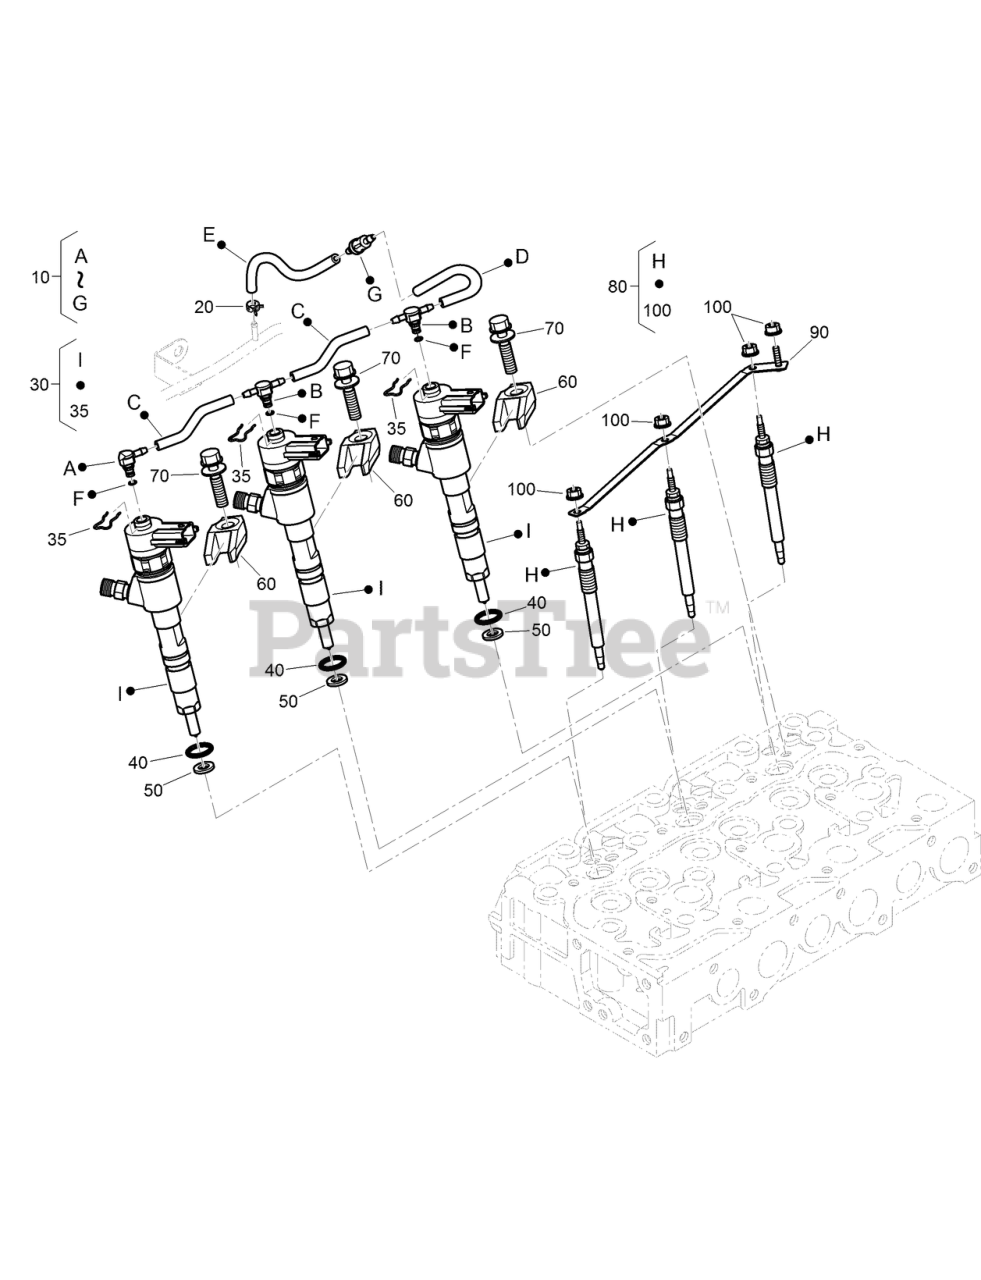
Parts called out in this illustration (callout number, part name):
10	OVER FLOW TUBE ASM
20	CLAMP-HOSE
30	INJECTOR ASM
40	O-RING
50	PACKING
70	BOLT ASM
80	PLUG-GLOW
90	CORD-PLUG, GLOW
100	NUT-FLANGE
